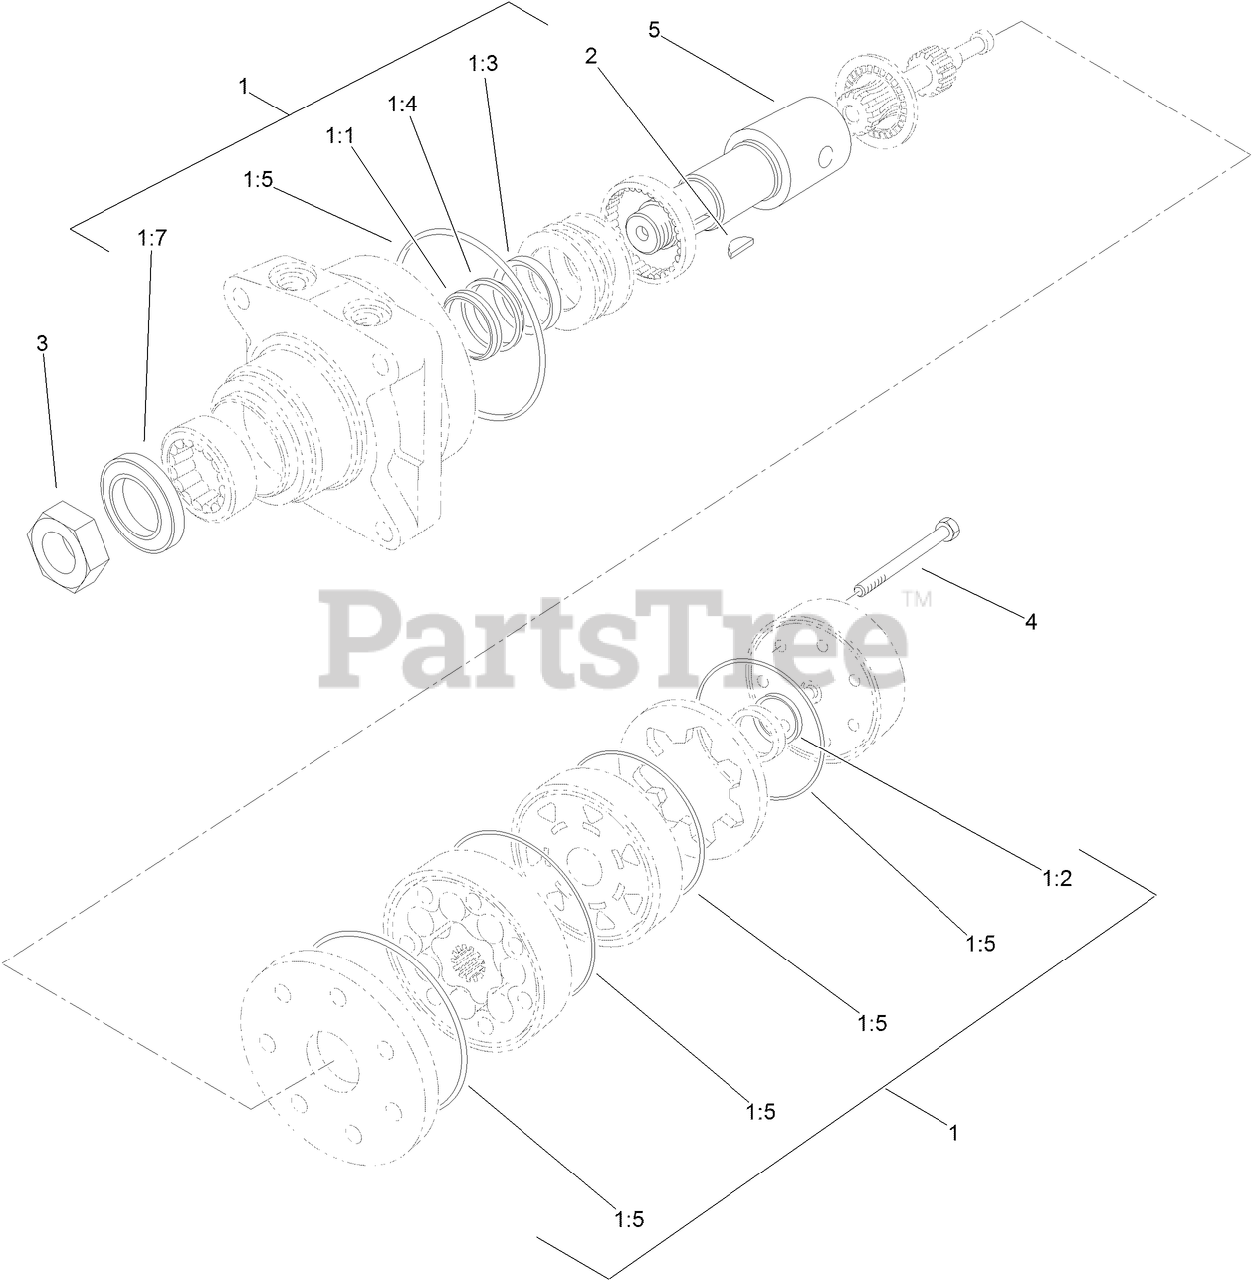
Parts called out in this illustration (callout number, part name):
1	SEAL KIT
1:1	Ring-Back Up
1:2	Seal-Commutator
1:3	SEAL-SHAFT (VITON)
1:4	WASHER-BACK UP, STEEL
1:5	RING-SEAL (VITON)
1:7	Seal-Dirt and Water
2	KEY-WOODRUFF
3	NUT-MOTOR, WHEEL
4	BOLT-SPECIAL
5	SHAFT-COUPLING
